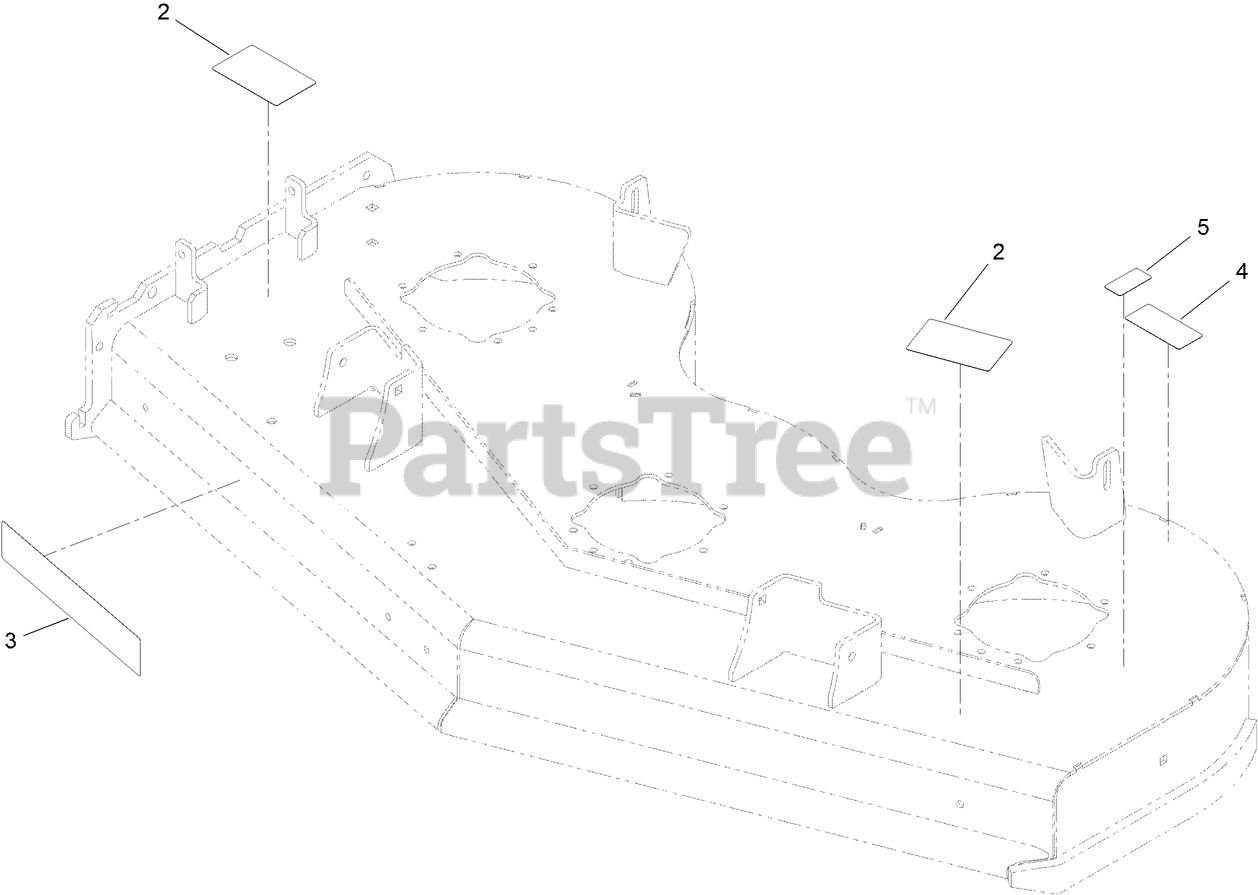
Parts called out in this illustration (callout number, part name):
2	DECAL-DANGER, CE
4	DECAL-DANGER
5	DECAL-NO SPRAY
